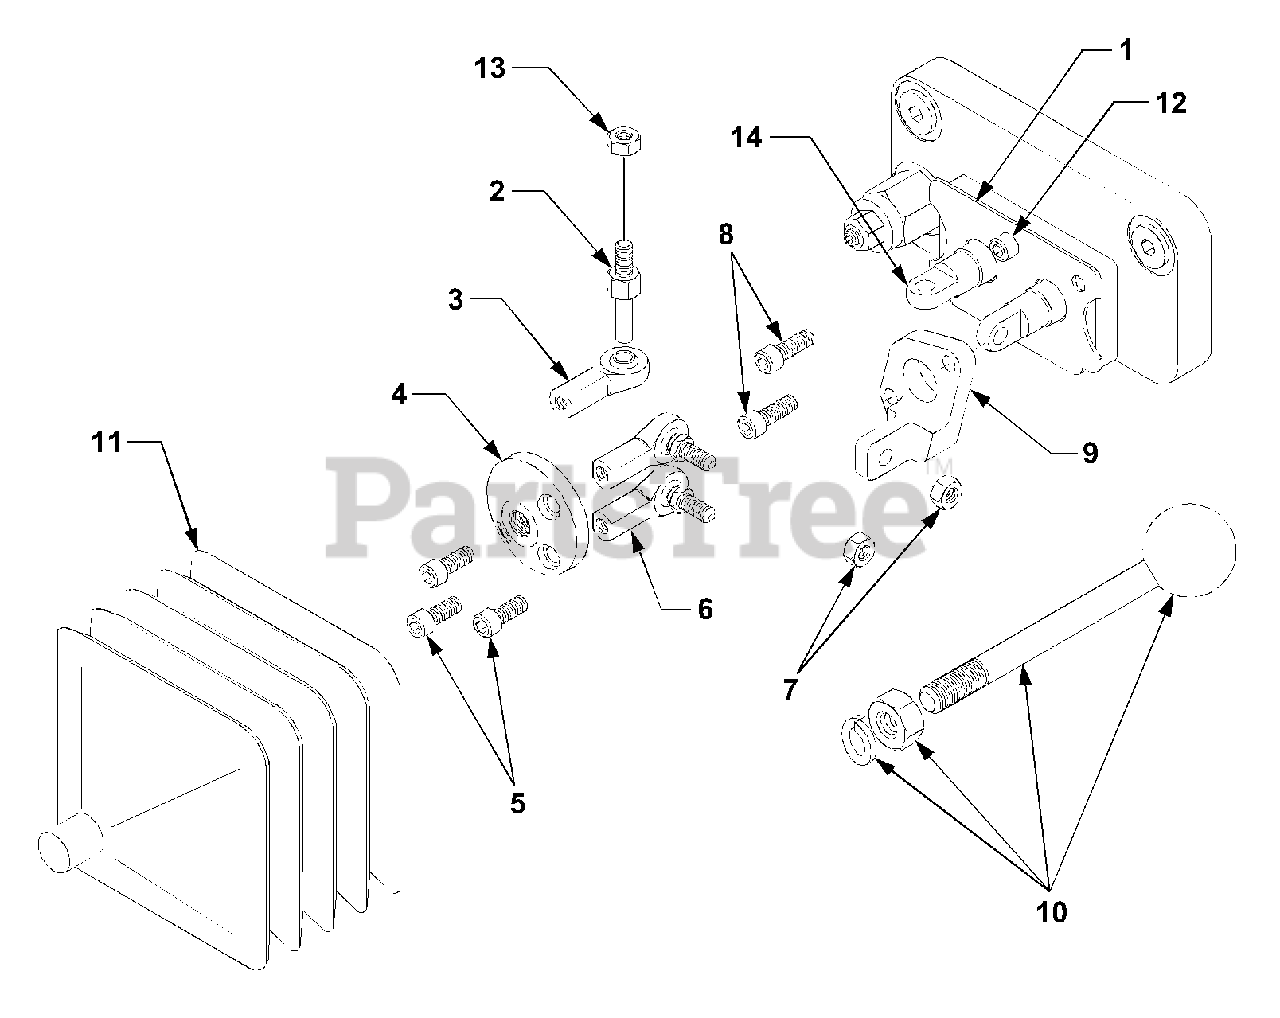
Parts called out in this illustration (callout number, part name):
1	Mounting Plate
4	Adapter Plate
6	Rod End Assembly
7	Hex Nut (Coarse Thread)
13	Hex Nut (Fine Thread)
14	Spool End Adapter
